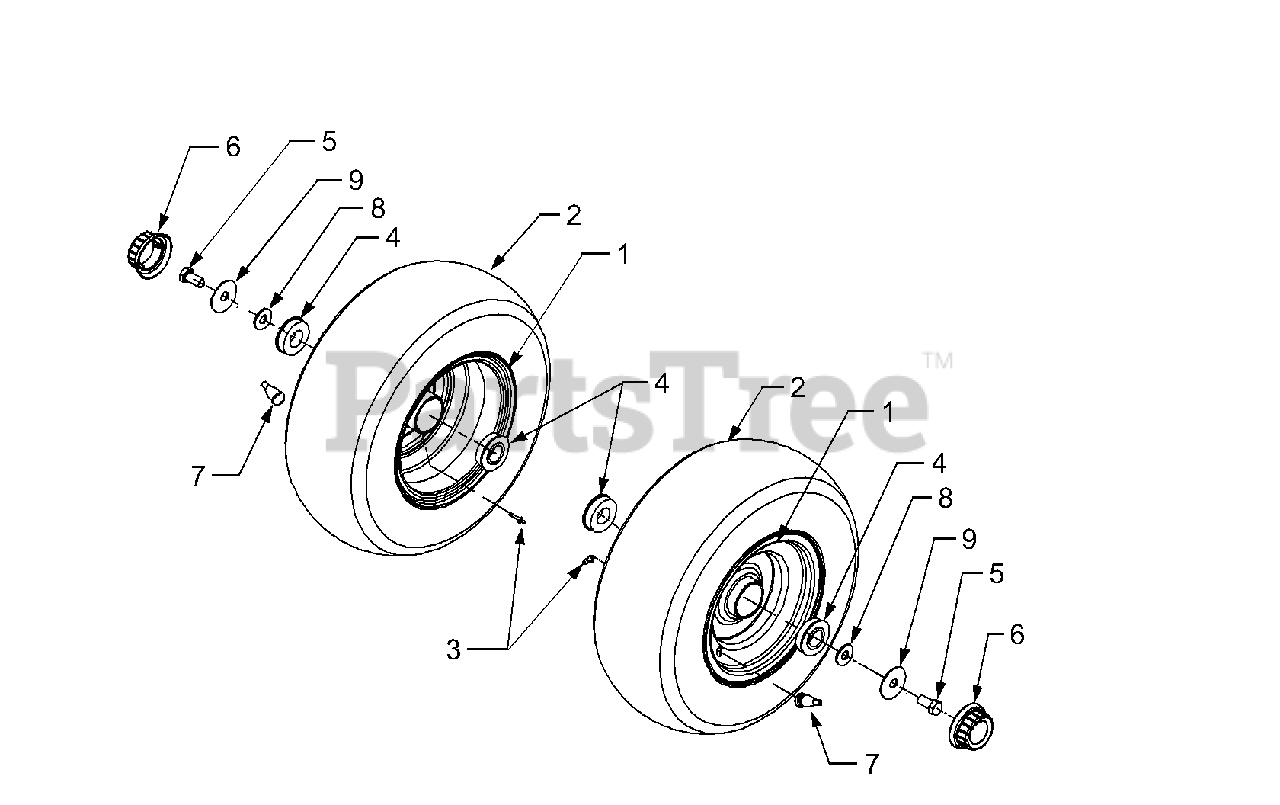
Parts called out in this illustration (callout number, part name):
1	Rim Assembly, Wheel
2	Tire, Turf, 16 x 7.5 x 8.0
3	Lube Fitting
4	Bearing, Ball
5	Screw, Hex Cap, 1/2-13 x 1.0 GR5
6	Hubcap
7	Valve, Tubeless Air
8	Washer, Flat, .531 x 1.25 x .1
9	Washer, Flat, .535 x 1.92 x .060
